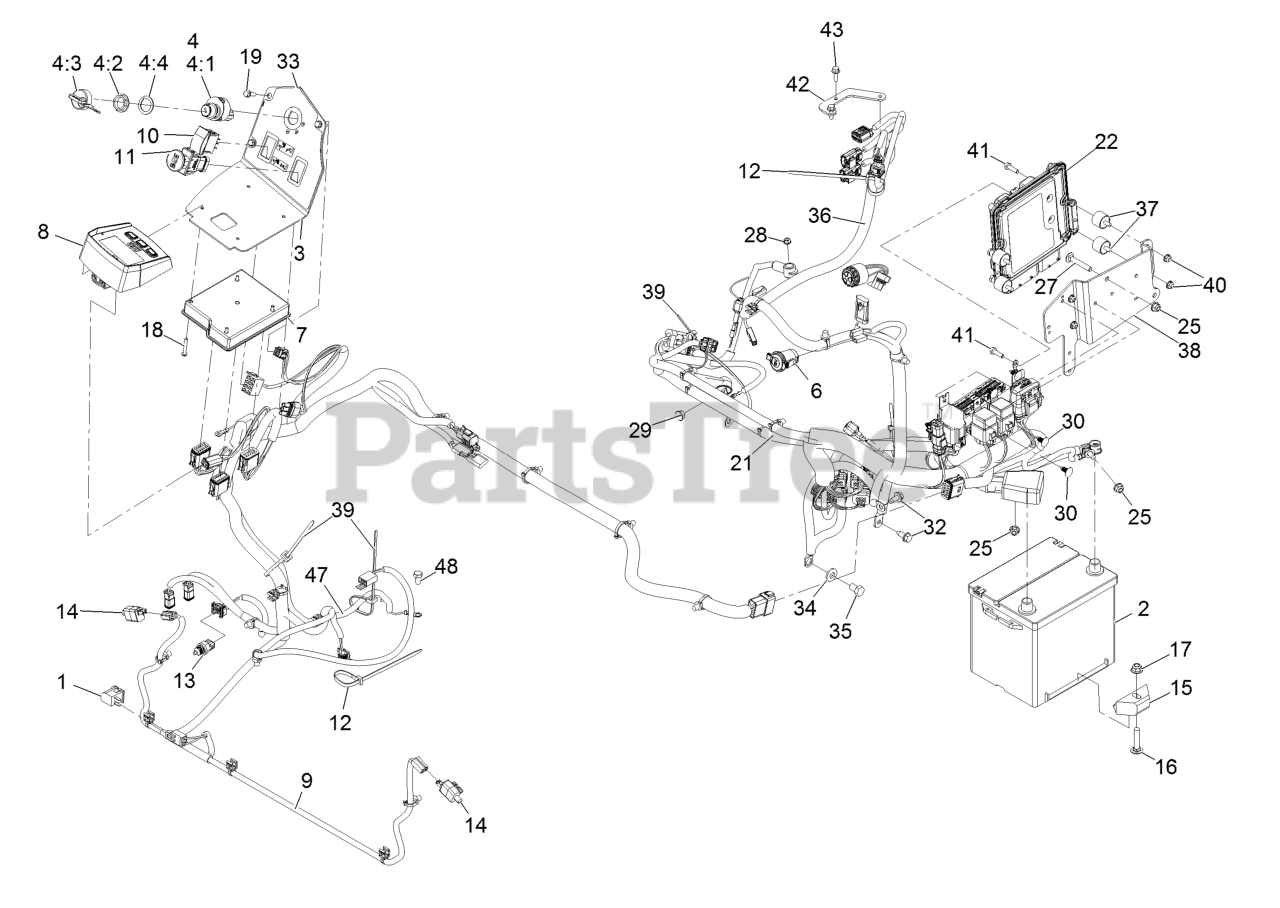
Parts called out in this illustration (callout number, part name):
2	Battery-Dry
3	Plate-Console
4	Ignition Switch ASM
4:1	Switch-Ignition
4:2	Nut-Mounting
4:3	Ignition Key Set
4:4	Washer-Backup
6	Port-Power, 12V
7	Module-Mcu
8	Module, Ldu
9	Harness-Wire
10	Switch, (On)-Off-(On)
11	Switch-PTO, Sealed
12	Tie-Cable 7 15/16 (Large)
13	Sensor-Temperature
15	Retainer-Battery
16	Bolt-Carriage 3/8-16 X 1 3/4
17	Nut-Nyloc 3/8-16 Flg
18	Screw-PPH
19	Screw-Machine 1/4-20 X 3/4
21	Cable-Battery
22	E C U ASM
25	Nut-Nyloc 5/16-18 Flg
27	Bolt-Carriage 3/16-18 X 2
28	Nut-Hex M6-1 Flg
30	Plug-Plastic
32	Screw-HWH 5/16-18 X 3/4 Tf
33	Decal-Control Panel
34	Washer-Spring Disc 3/8
35	Screw-HH
36	Harness-Wire
37	Mount-Cylindrical
38	Mount-Control Unit, Engine
39	Tie-Cable
40	Nut-Nyloc 1/4-20 Flg
41	Screw-HH 1/4-20 X 7/8
42	Bracket-Wiring, Engine
43	Screw-HHF
47	Harness-Wire, Jumper
48	Bolt
